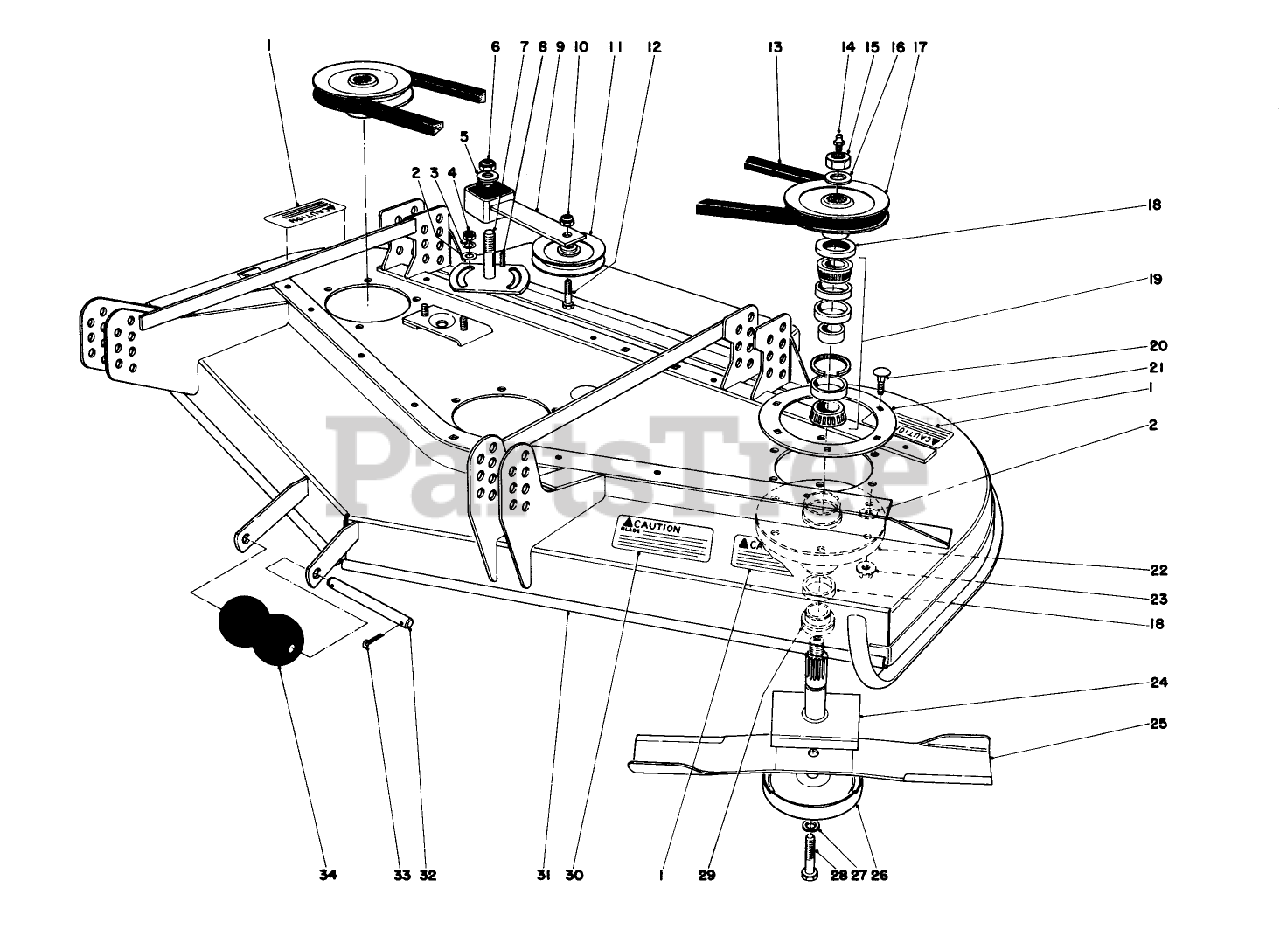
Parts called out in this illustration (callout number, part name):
1	DECAL-CAUTION, BLADE
2	WASHER-FLAT
3	WASHER-LOCK
4	NUT-JAM
5	WASHER-FLAT
6	NUT-LOCK, NI
7	PLATE-IDLER
8	KEY-SQUARE
9	IDLER ARM ASM
10	NUT-HEX
11	Idler Pulley
12	SCREW-HH
13	V-BELT
14	FITTING-GREASE
15	NUT-HEX
16	WASHER
17	PULLEY AND HUB ASM
18	SEAL-OIL
19	BEARING ASM
20	SCREW-CARR
21	SUPPORT-DECK, RING
22	Housing-Spindle
23	NUT-HF
24	SHAFT
25	Blade
26	Cup-Scalp
27	WASHER-LOCK
28	SCREW-BLADE
29	SPACER
30	Decal-Caution
31	CUTTER DECK WA RO
32	SHAFT-ROLLER
33	PIN-COTTER
34	ROLLER
